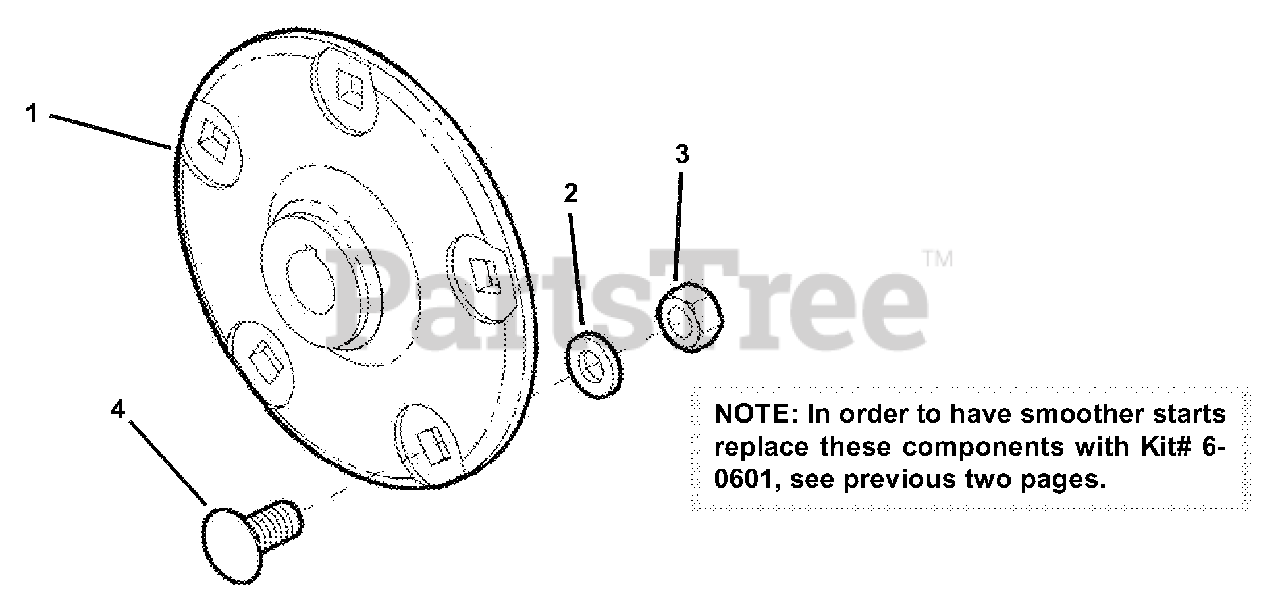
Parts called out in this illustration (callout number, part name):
1	HUB
2	WASHER, 5/16 Split Lock
3	NUT, 5/16-18 Hex
4	BOLT, 5/16-18 x 3/4" Square Neck Carriage
